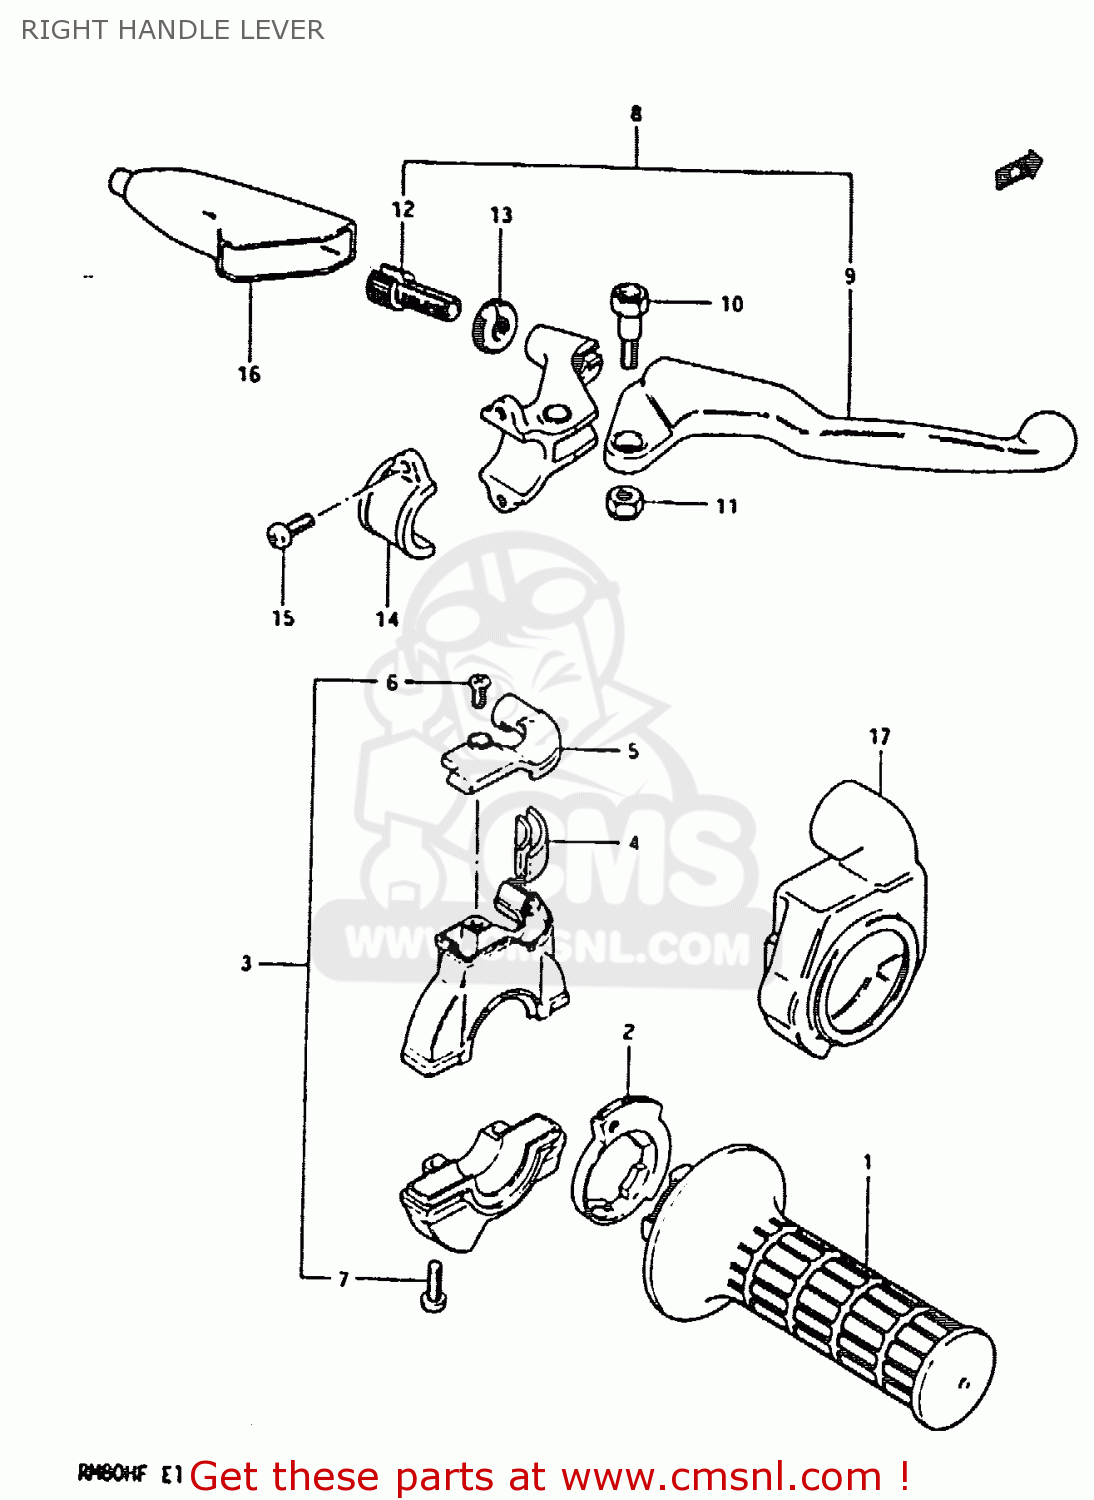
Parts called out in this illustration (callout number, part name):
1	GRIP,THROTTLE
2	ROTOR,THROTTLE GRIP
3	CASE ASSY,THROTTLE
4	GUIDE PIECE,THROTTLE
5	COVER,THROTTLE CASE
6	SCREW
7	SCREW
8	LEVER ASSY,BRAKE
9	LEVER,BRAKE
10	BOLT,LEVER
11	NUT 6MM
12	ADJUSTER,CABLE
13	NUT,CABLE ADJUSTER
14	BRACKET,CLUTCH LEVER HOLDER
15	SCREW
16	COVER,CLUTCH LEVER
17	COVER,THROTTLE CASE
